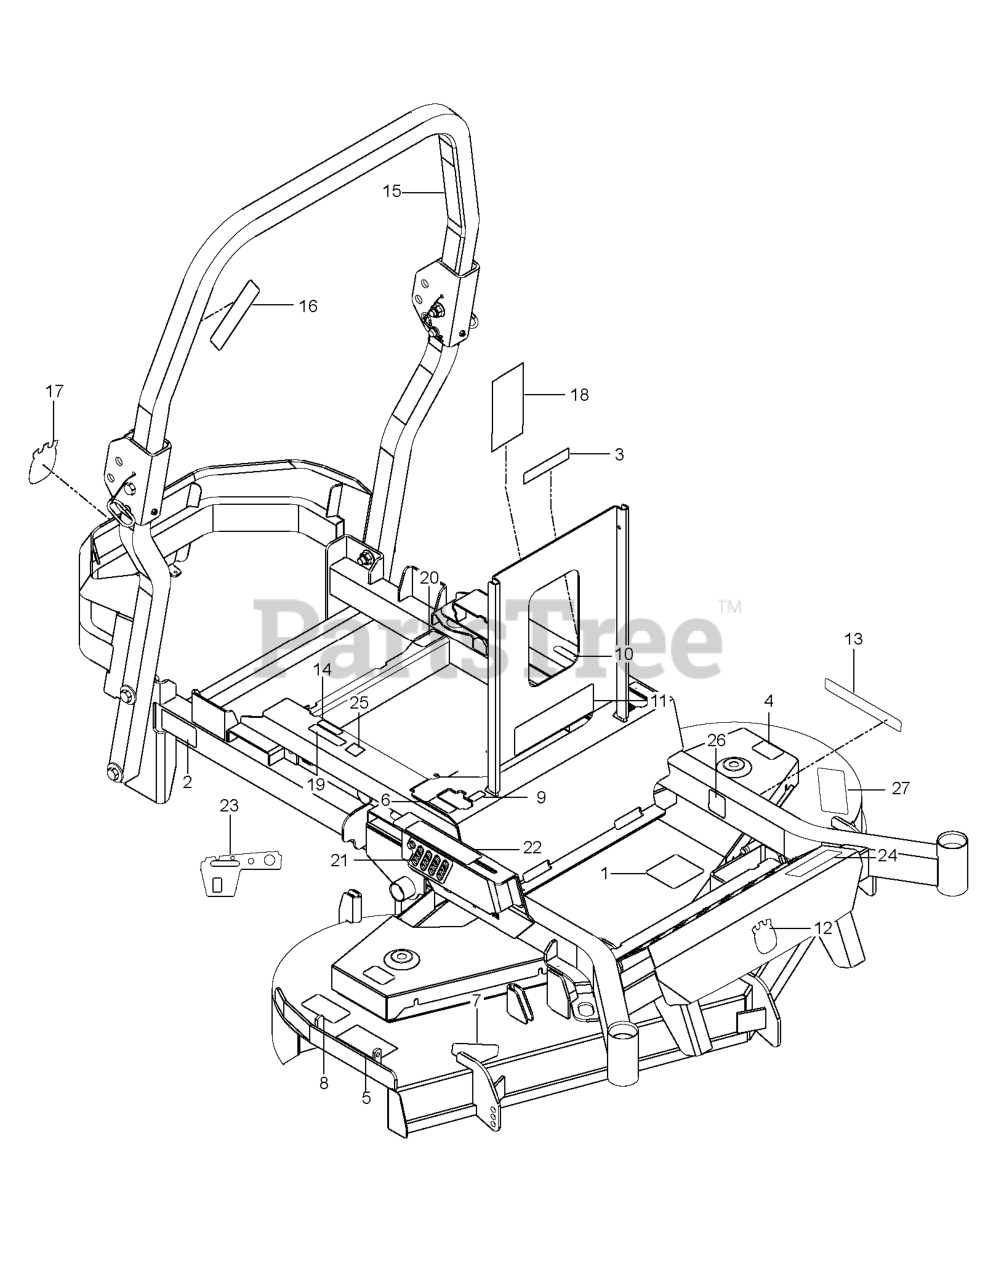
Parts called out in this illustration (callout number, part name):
1	DECAL, BELT ROUTING
2	DECAL, BELT DRIVE
3	EURO DECAL-BATTERY WARNIN6
4	DECAL.DECK.6MIL.EURO.NOSTEP
5	DECAL, EURO SEVERING
6	DECAL.ZTR.MOTCONTRL.SYMBOL.HUS
7	DECAL, DECK DEFLECTOR, WARNING
8	DECAL.DECK.6MIL./DEF.SHLD.WARN
9	DECAL.STR.S.T.SYSMBOLONLY.2014
10	DECAL.ZTR.PARKBRAK.SYMBOL.2014
11	DECAL.ZTR.WARNING.SMARTIGNITIN
12	DECAL.AUGER.HUSQ.CROWN.SNOW
13	RP.DECAL.BADGE.170MM.TEXTLOGO
14	DECAL, FUSE
15	DECAL, ROPS
16	DECAL, ROPS, WARNING
17	DECAL, CROWN H, 110MM
18	DECAL, SERVICE
19	DECAL, WARNING SPARK ARRESTOR
20	DECAL, FUEL
21	DECAL, HEIGHT
22	DECAL, RELEASE LEVER
23	DECAL, CONTROL, GAS
24	DECAL.P-ZT.54
25	DECAL CERTIFICATION DECAL EMCC
26	DECAL.80.DBA.AUSTRALIA
